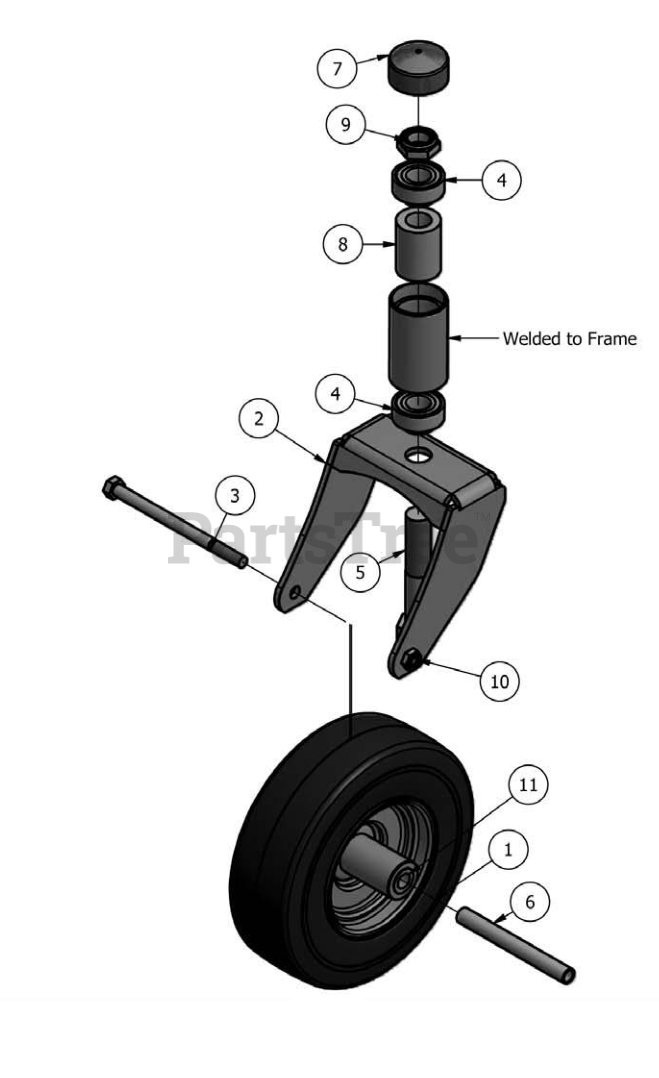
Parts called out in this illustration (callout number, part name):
1	11 x 6.00 5 Front tire (Smooth) & Wheel Assembly -
2	Front Fork
3	1/2 x 7 Hex Bolt Grade 5
4	Bearing Caster
5	1-14 x 5 Hex Bolt Grade 8 Zinc Yellow
6	Front Wheel Spanner
7	Rubber Bearing Cap
8	MZ Caster Bearing Spacer
9	1-14 Nylock Jam Nut
10	1/2-20 Nylon Insert Jam Locknut Zinc Orange Zinc
11	Wheel Bearing MZ
